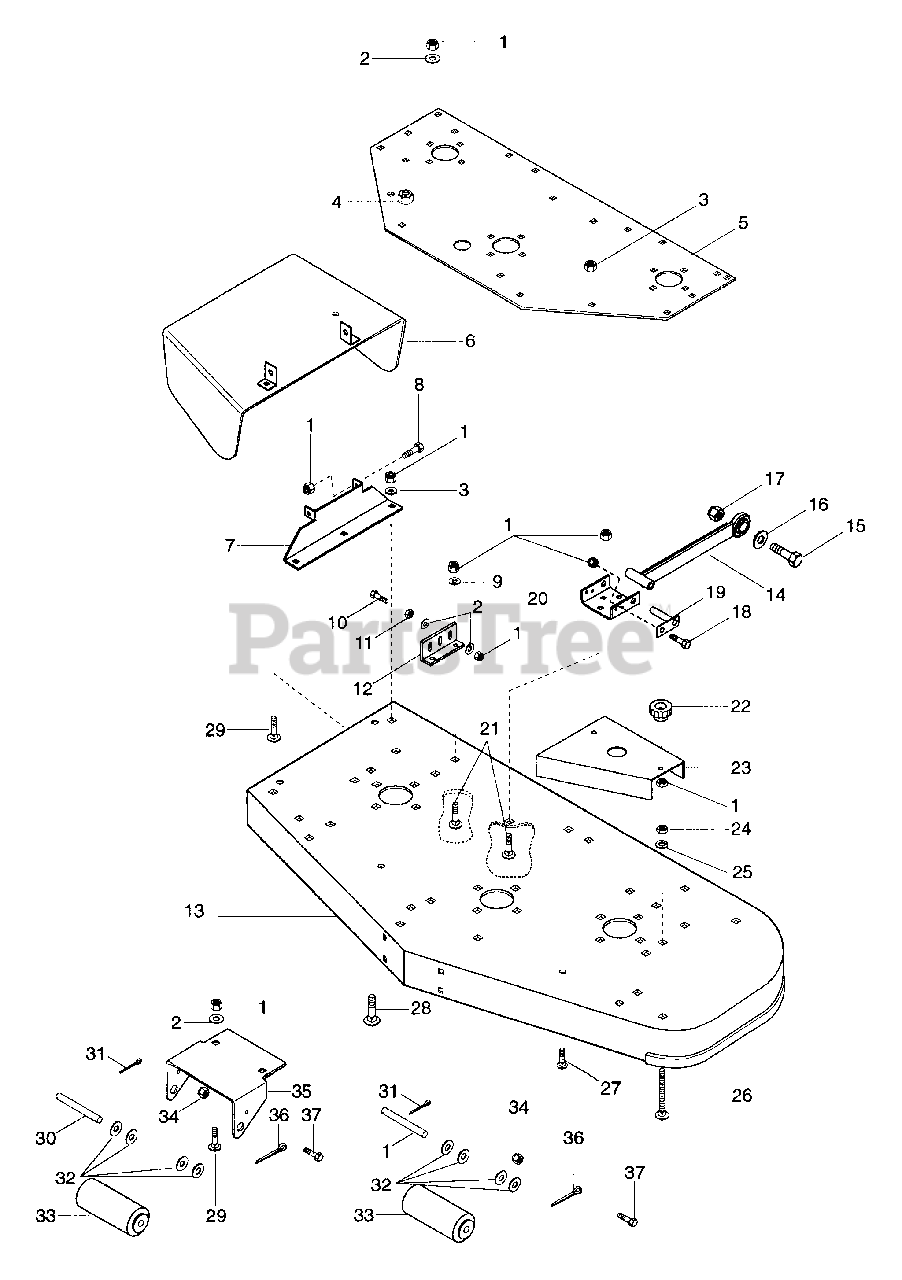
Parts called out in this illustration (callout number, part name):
1	Nut-Locking-Nylon .375-16 Grade 2
2	Washer-Flat-Steel .406 x .812 x .065
3	Nut-Locking-Nylon .312-18 Grade 2
4	Nut-Locking-Nylon .50-13 Grade 2
5	Plate, 60" Support
6	Weldment, Discharge Chute
7	Bracket, Discharge
8	Bolt-Hex .38-16 x 1.00 Grade 5
9	Bushing .406 x .750 x .188
10	Bolt-Hex .38-16 x 1.50 Grade 5
11	Nut-Hex .375-16 Grade 2
12	Bracket, Mower Mounting
13	Weldment, Deck 60" Mower PM200
14	Weldment, Mower Mounting Arm
15	Bolt-Hex .87-9 x 2.75 Grade 5
16	Washer-Flat-Steel .094 x .250 x .020
17	Nut-Locking .875-9
18	Bolt-hex .38-16 x .75 Grade 5I
19	Weldment, Mower Mounting Pin
20	Bracket, Mower Mounting
21	Bolt-Round Head Square Neck .38-16 x 1.25
22	knob
23	Guard, Pulley L.H. 60" Mower
23	Guard, Pulley R.H. 60" Mower
24	Nut-Hex .312-18 Grade 2
25	Washer-Lock .313 x .078
26	Bolt-Round Head Square Neck .31-18 x 3.50
27	Bolt-Round Head Square Neck .31-18 x .62
28	Bolt-Round Head Square Neck .50-13 x 1.00
29	Bolt-Round Head Square Neck .38-16 x 1.0
30	Shift, Center Roller
31	Pin-Cotter .25 x 1.00
32	Washer-Flat-Steel .656 x 1.312 x .095
33	Roller, Gage
34	Nut-Locking-Nylon .250-20 Grade 2
35	Bracket, Roller R.H.
36	Pin-Cotter .250 x 2.00
37	Bolt-Hex .25-20 x .75 Grade 5
